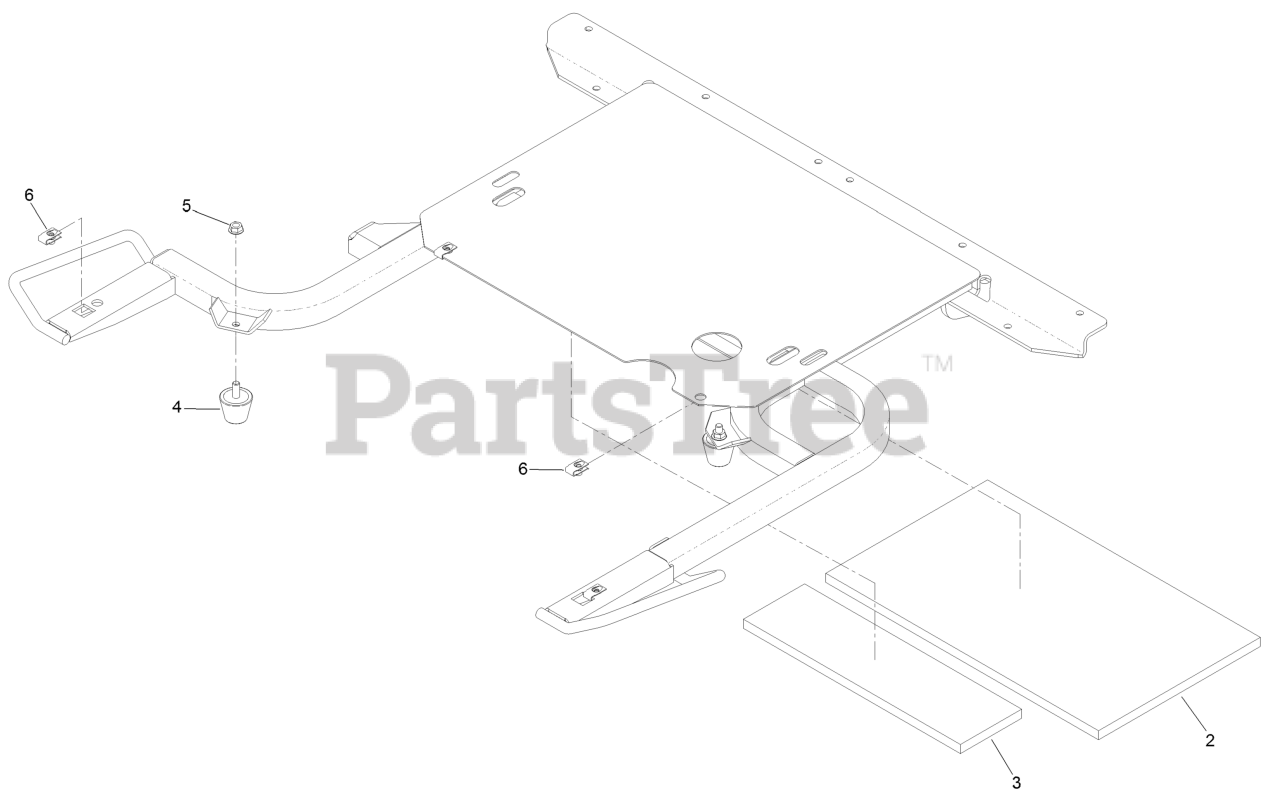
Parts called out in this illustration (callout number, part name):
2	Insulation-Foam Pad, Rear
3	Insulation-Foam Pad, Front
4	Bumper-Rubber
